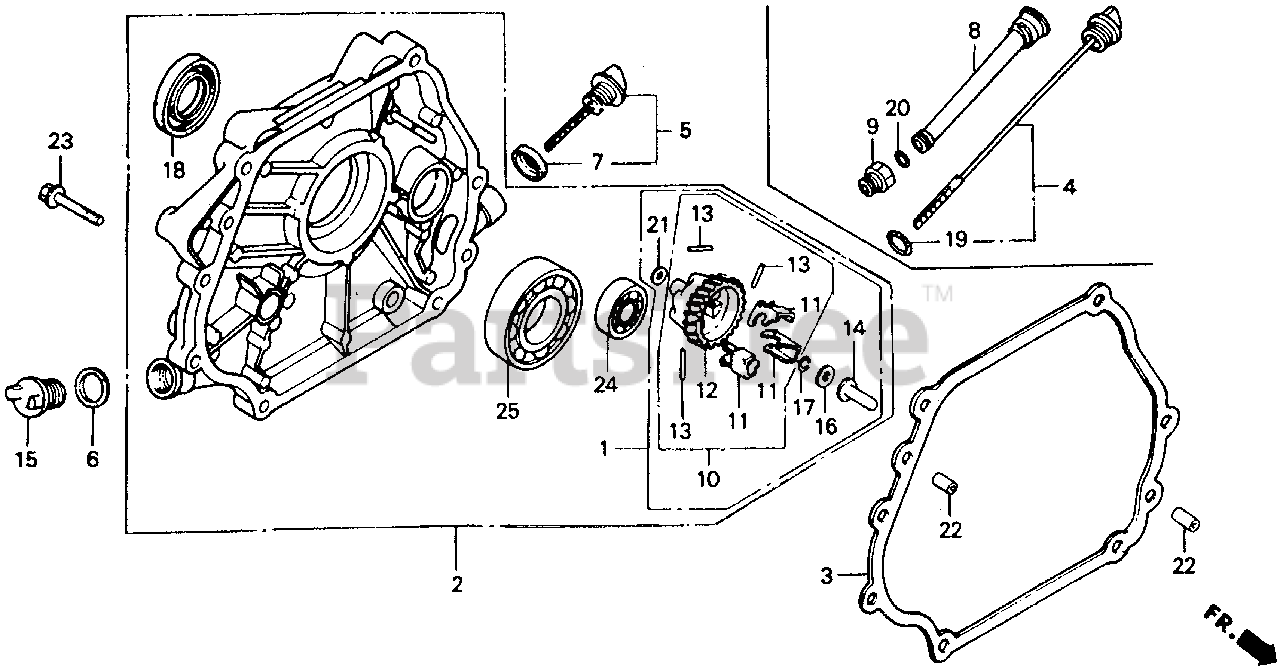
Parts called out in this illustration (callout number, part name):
1	GOVERNOR KIT
2	COVER ASSY., CRANKCASE (S-TYPE)
3	GASKET, CASE COVER
5	CAP ASSY., OIL FILLER
6	GASKET, OIL FILLER CAP
7	GASKET, OIL FILLER CAP
10	GOVERNOR ASSY.
11	WEIGHT, GOVERNOR
12	HOLDER, GOVERNOR WEIGHT
13	PIN, GOVERNOR WEIGHT
14	SLIDER, GOVERNOR
15	CAP, OIL FILLER
15	CAP, OIL HOLE
16	WASHER (6X16)
17	CLIP, GOVERNOR HOLDER
18	OIL SEAL (35X52X8)
21	WASHER, PLAIN (6MM)
22	PIN, DOWEL (8X12)
22	PIN A, DOWEL (8X12)
23	BOLT, FLANGE (8X40)
24	BEARING, RADIAL BALL (6202)
25	BEARING, RADIAL BALL (6207)
